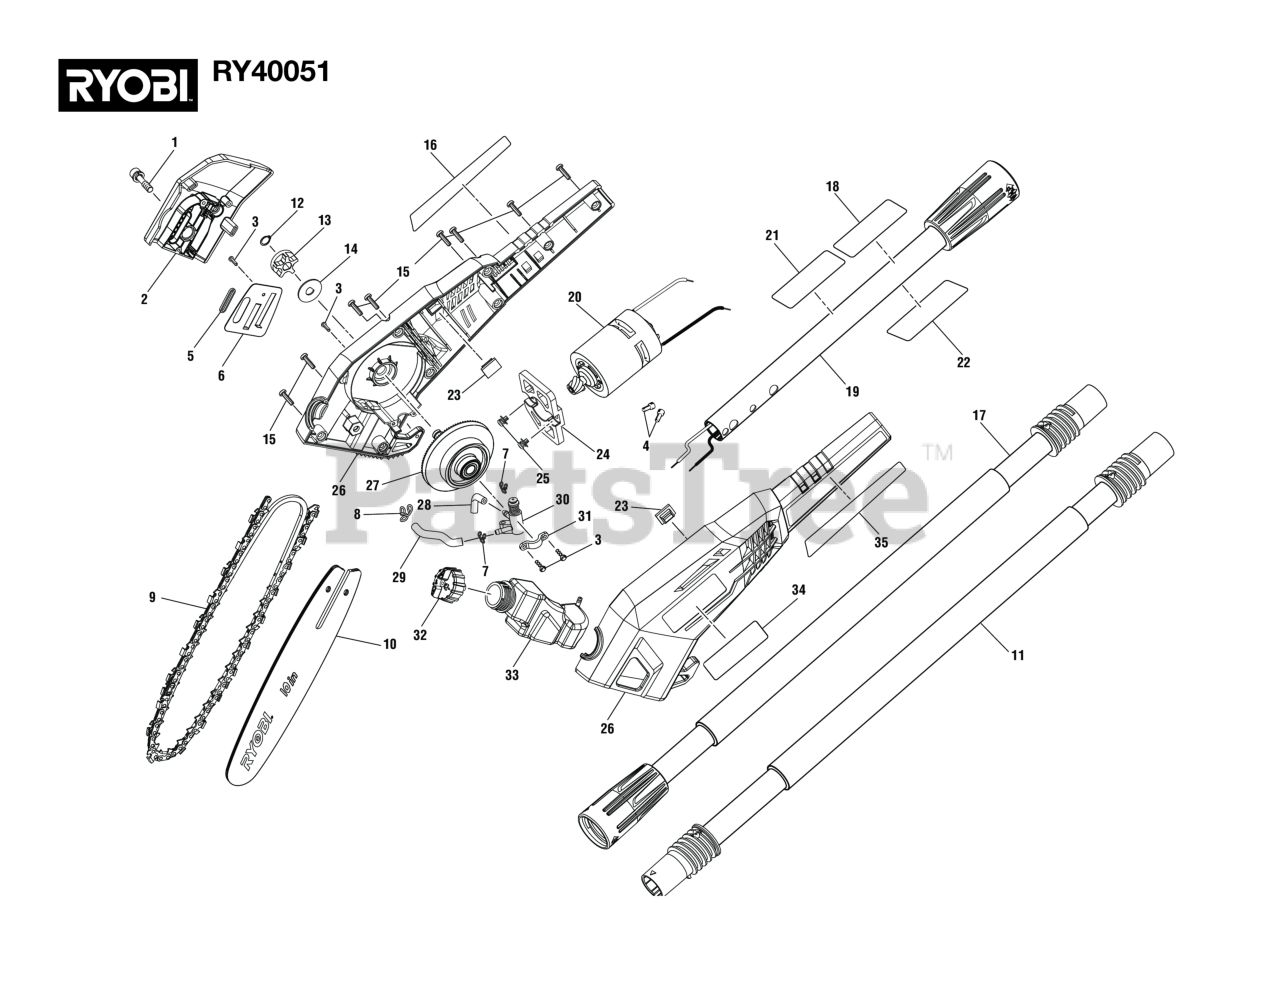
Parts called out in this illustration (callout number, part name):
1	Screw w/Washer (M6 x 25 mm, Rd. Hd. )
2	Chain Cover Assembly
3	Screw (M3 x 10 mm)
4	Wire Connector (Closed End)
5	Oil Outlet Seal Ring
6	Guide Bar Plate
7	Clip-hose (Id 4.9)
8	Clip-hose
10	Guide Bar
11	Boom Assembly
12	Retaining Ring
14	Cover Plate (Internal "D" Washer)
15	Screw (M4 x 18 mm, T20 Torx Pan Hd.)
16	40V Lithium Label (Right)
17	Extended Boom Assembly
18	Icon Warning Label (English)
19	Upper Pole Assembly
20	Motor Assembly
21	Data Label
22	Warning Label (French/Spanish)
23	Rubber Bumper
24	Mounting Plate
25	Screw w/Washer (M5 x 9 mm, Pan Hd.)
26	Motor Housing Assembly
27	Output Shaft Assembly
28	Inlet Tube
29	Outlet Tube
30	Oil Pump Assembly
31	Pump Clamp
32	Oil Tank Cap Assembly
33	Oil Tank Assemlby
34	40V Lithium Label (Right)
35	40V Lithium Label (Left)
